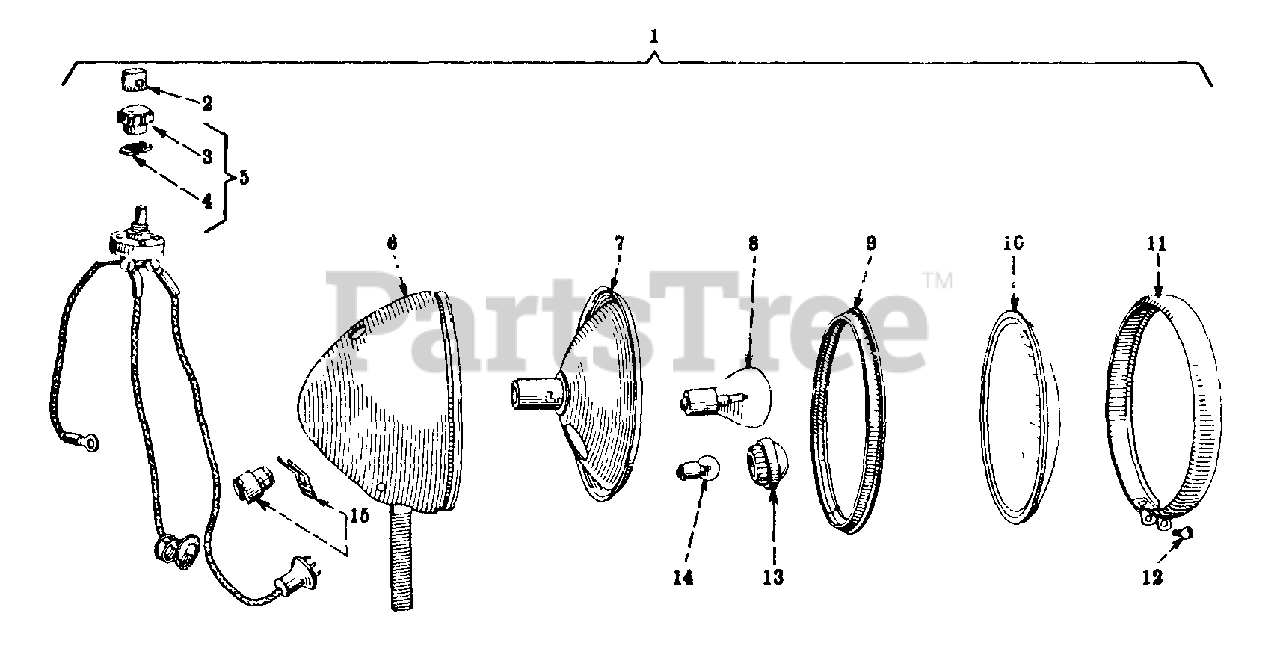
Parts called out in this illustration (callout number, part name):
1	LIGHT ASSY. COMBINATION REAR AND TAIL 6 VOLT
2	KNOB, SWITCH W/SCREW - METAL
3	KNOB, SWITCH-PLASTIC
4	NUT, SWITCH RETAINING
5	SWITCH ASSY. LIGHT LESS WIRING
6	BODY, REAR LIGHT
7	REFLECTOR, REAR LIGHT
8	LAMP, NO 1133 -6 VOLT-
9	GASKET REAR LIGHT
10	LENS REAR LIGHT
11	MOULDING, REAR LIGHT
12	SCREW REAR LIGHT DOOR
14	LAMP, NO. 51 - 6 VOLT
15	PACKAGE, TERMINAL PLATE ASSY.
